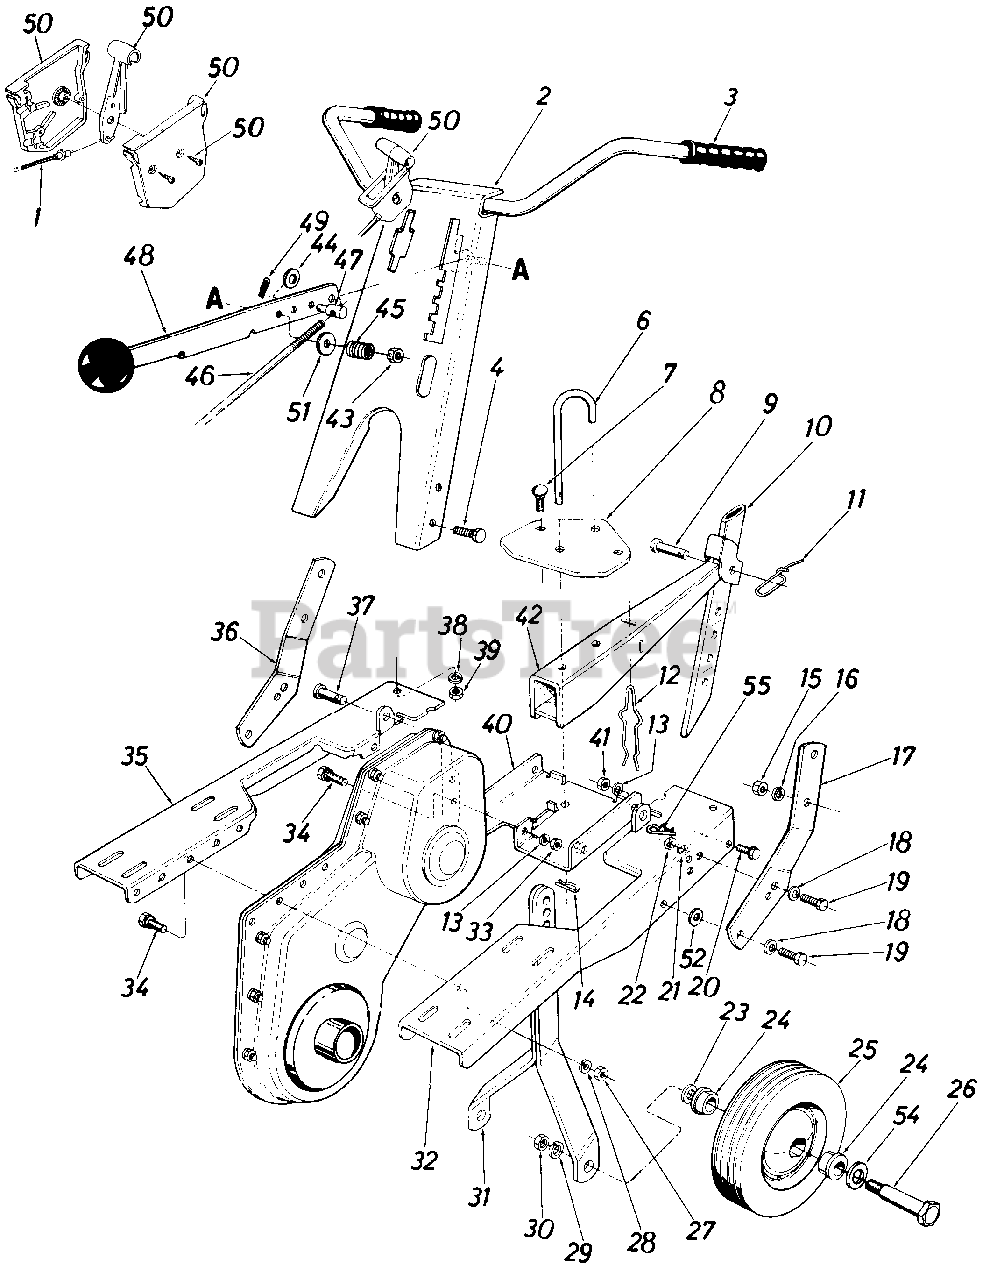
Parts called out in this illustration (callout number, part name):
1	Throttle Control Wire
2	Handle Ass'y.
3	G ri p
4	Hex Scr. 3/8-16 x 1.00 Lg.
6	"U"-Clevis Pin .500" Dia.
7	Carr. Bolt 5/16-18 x .75" Lg.*
8	"U"-Channel Plate
9	Clevis Pin 1/2" Dia.
10	Depth Bar
11	Spring Pin
12	Depth Bar Spring
13	L-Wash. 5/16" I.D.
14	Inter. Cotter Pin 1/2" Dia.
15	Hex Nut 3/8-16 Thd.
16	L-Wash. 3/8" I.D.
17	Handle Brkt.-L.H.
18	Bell. Wash. 3/8" I.D.
19	Hex Scr. 3/8-16 x 1.00" Lg.
20	Hex Bolt 5/16-18 x .75" Lg .
21	L-Wash. 3/8" I.D.
22	Hex Nut 3/8-16 Thd.
23	Belleville Wash. Hdn.
24	Flange Brg. w/Flats .631 I.D.
25	Wheel Assembly 10.0 x 1.75
26	Shld. Scr. .625" Dia. x 2.75" Lg. (1/2-20 Thd.)
27	Hex Nut 5/16-18 Thd.
28	L-Wash. 5/16" I.D.
29	L-Wash. 1/2" I.D.
30	Hex Elastic Insert Nut 1/2-20 Thd.
31	Wheel Brkt. Ass'y.
32	Engine"U"-Channel Ass'y.-L.H.
33	Hex Nut 5/16-18 Thd.
34	Hex Sems Scr. 5/16-18 x 1.00" Lg.
35	Engine "U"-Channel Ass'y.-R.H.
36	Handle Brkt.-R.H.
37	Clevis Pin
38	L-Wash. 5/16" I.D.
39	Hex Nut 5/16-18 Thd.
40	"U"-Channel Brkt. Ass'y.
41	Hex Nut 5/16-18 Thd.
42	Tailpiece Ass'y.
43	Hex Cent. L-Nut 5/16-18 Thd.
44	Fl-Wash. .344 I.D. x .87 O.D.
45	Spring
46	Control Rod
47	Ferrule
48	Shift LeverAssembly w/Knob
49	Inter. Cotter Pin 1/2" Dia.
50	Throttle Control Box Complete
51	Belleville Washer
52	Flat Washer
54	Flat Washer (Hardened)
55	Cotter Pin
